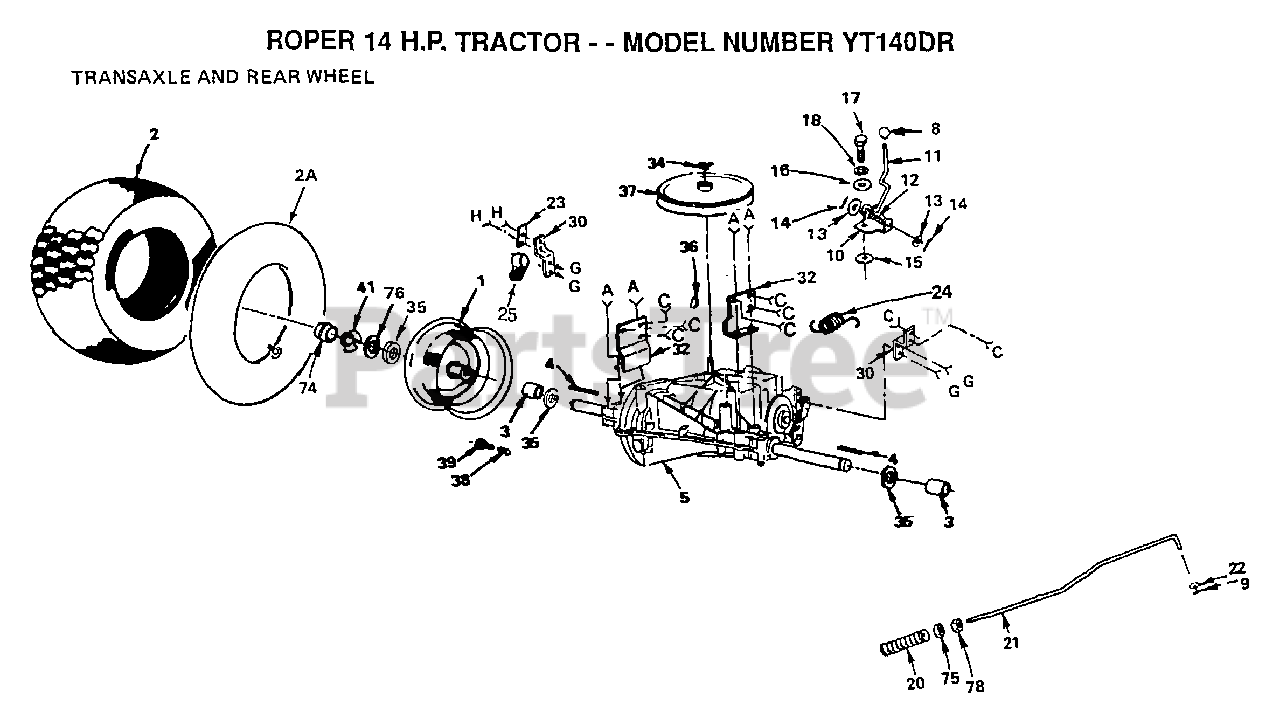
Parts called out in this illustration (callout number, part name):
2A	TUBE.18X9.5-8
3	SPACER LT
8	KNOB.DUCKHEAD.1/2
9	COTTER PIN
10	PLATE SHIFT LT
12	SPRING LT
13	WASHER
14	PIN COTTER 1/8
15	WASH-SHFT PLT LT
16	WASHER LT
18	LOCKWASHER
20	SPRING ROD LT
21	BRAKE ROD LT
22	WASHER
23	PLATE-STRAP LT
25	CLIP T
30	"STRAP, TORQUE LT"
32	BRACKET LT
35	WASHER
38	VALVE CAP
39	VALVE STEM LT
41	E-RING LT
74	HUB CAP
76	WASHER
78	NUT
